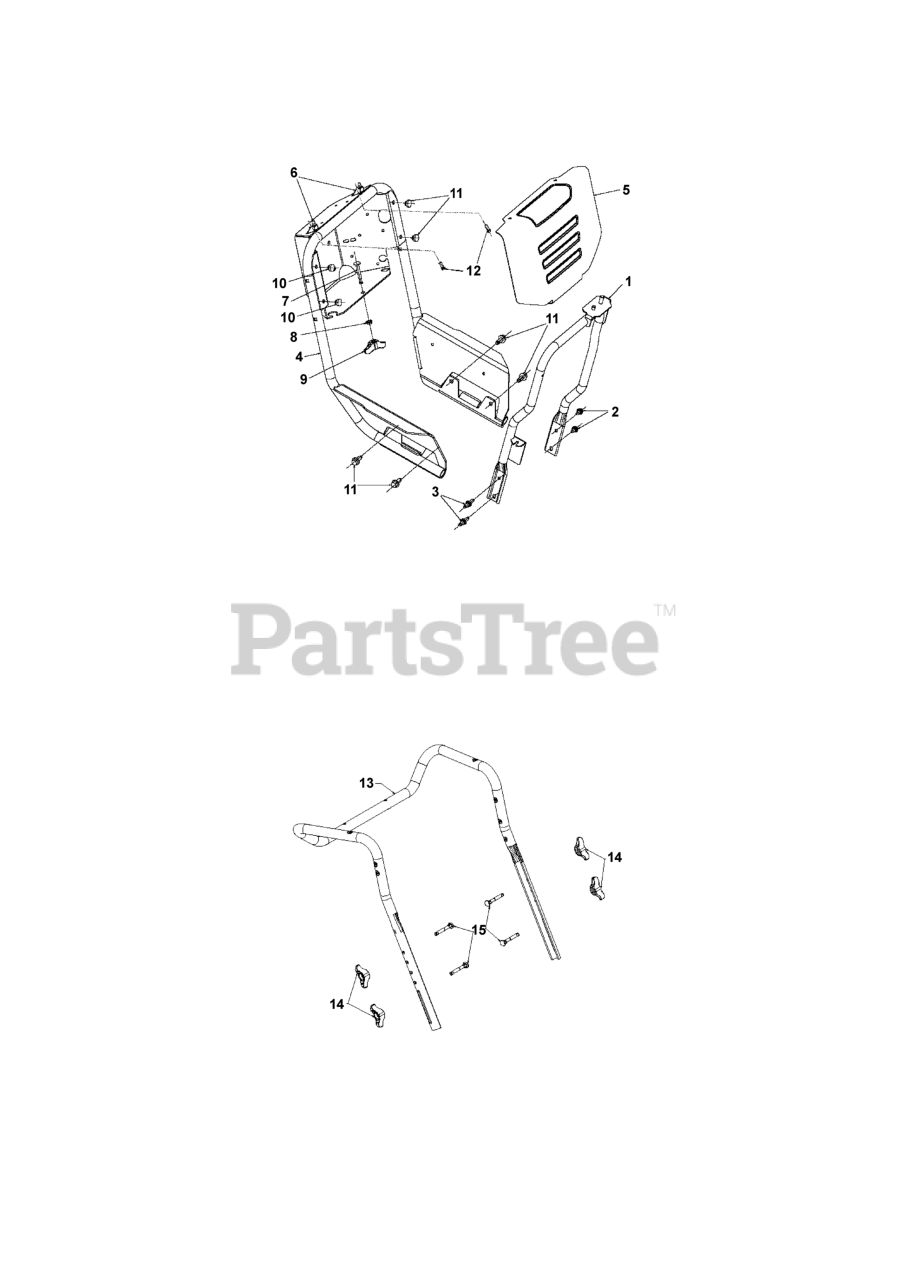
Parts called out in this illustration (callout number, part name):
1	SUPPORT WELDMENT, CHUTE PAINTE
2	BOLT.5/16HEX.WHS.HD
3	STUD BOLTED HEX HEAD
7	BOLT.HAND.PIV.ADJ.313-18.21EFF
8	NUT.FLANGE.5/16
8	GSPW Hardware
10	GROMMET.BUMPER
11	SCREW HEXAGON HEAD FLANGE 3/8-
12	SCREW.HWH.13-16-5.8.BZP
13	HANDLE.UPPER.498
14	KNOB, DEFLECTOR
15	BOLT.CARRIAGE.5/16-18 X 2.25
